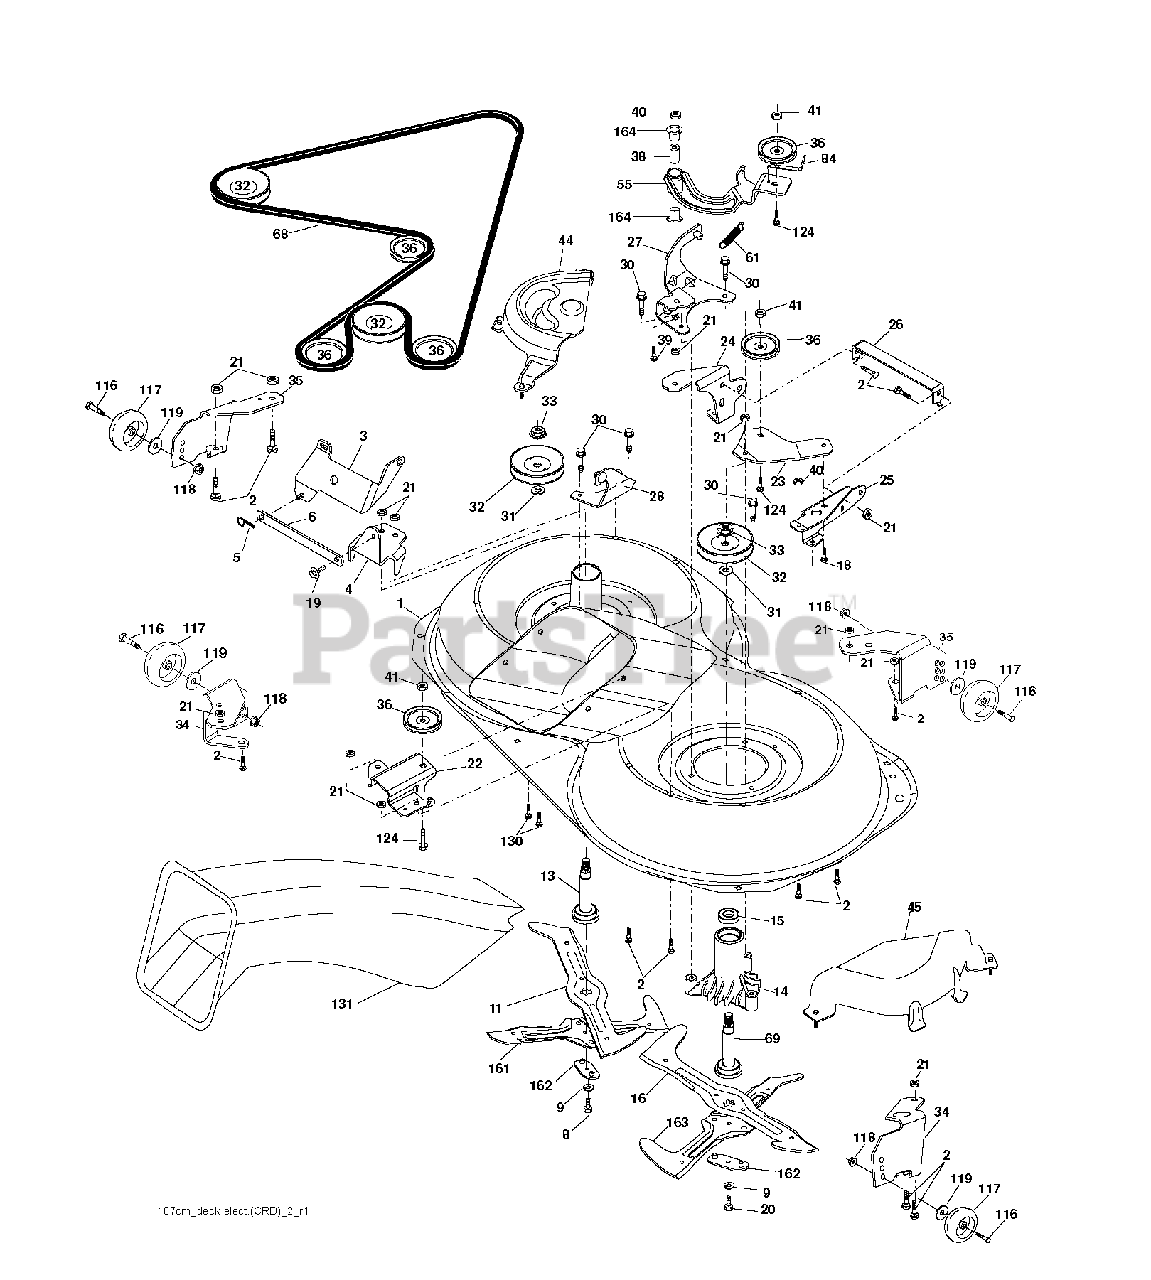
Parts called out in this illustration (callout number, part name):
2	BOLT
3	BRACKET.ASM.BAR.SWAY.CHASS
5	RETAINER-SPRNG RB
6	BAR SWAY
9	LOCKWASHER
11	BLADE.3N1.LH.CRD
13	SHAFT ASM VENT
14	HSG MANDREL
16	BLADE.3N1.RH.CRD
19	BOLT SHD 5/16-18
21	LOCKNUT
22	BRACKET
23	BRACKET
27	BRACKET
30	SCREW, WASHER HEAD
31	WASHER.SPACER.MANDREL
33	NUT.FLANGE.LOCK.TOP
36	PULLEY.IDLER.4.25
40	LOCKNUT
41	NUT LOCK FLG 3/8-16 UNC
55	ARM IDLER
68	HEX-BELT 107 MOWER
69	SHAFT.ASM.W/LWR.BRG.RH.THREAD
84	KEEPER, BELT IDLER
116	BOLT.SHOULDER.3/8-16X3-5/8
117	WHEEL. GUAGE RALLY
118	NUT LOCK FLG 3/8-16 UNC
124	BOLT.3/8-16X1.50
131	CHUTE BAGGER
164	BRNG T
